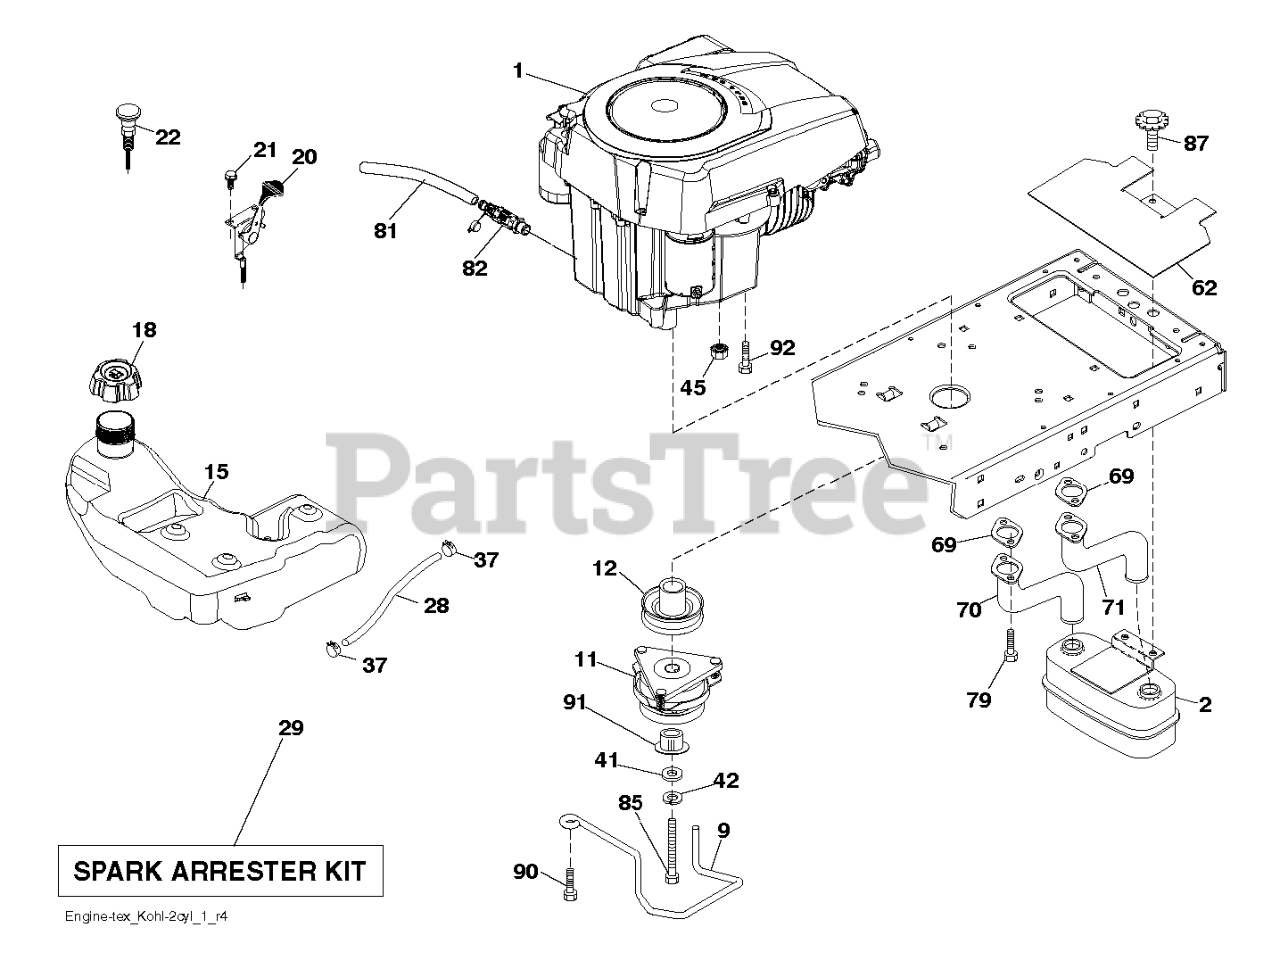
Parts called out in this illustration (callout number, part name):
2	MUFFLER.ASM.TWN.EXTNDED.DFLCTR
9	KEEPER.BELT.ENGINE.4.2
11	CLUTCH.ELECTRIC.LT.48"*
12	PULLEY.ENGINE.TUFFTORQ
15	RP_TANK.ASSY.3.GAL.EPA
18	CAP.ASM.FL.RITCH.3"E10.SYM.498
20	THROTTLE CONTROL
21	SCREW.#10 X 0.750.BOS
22	CONTROL.CHOKE.ERGO.PUSH-IN.BLA
28	LINE.FUEL.64"REAR.EMIS
29	KIT.SPARK ARRESTOR 794945 B&S
37	HOSE CLAMP
42	LOCKWASHER
45	NUT
62	SHIELD.HEAT.MUFFLER
69	GASKET.EXHAUST.KOHL.CV18-CV26
70	RP.PIPE-EXHAUST LH
71	RP.PIPE-EXHAUST RH
79	SCREW.SOCKET HD.5/16-1
81	TUBE, DRAIN OIL ASM.
82	VALUE.OIL.DRAIN
85	BOLT HEX 7/16-20X4-1/4"
87	BOLT 5/1618UNC X 3/4 W/ SEMS
90	SCREW 3/8-16X1
91	BUSHING.1.375OD
92	SCREW 3/8-16X1
